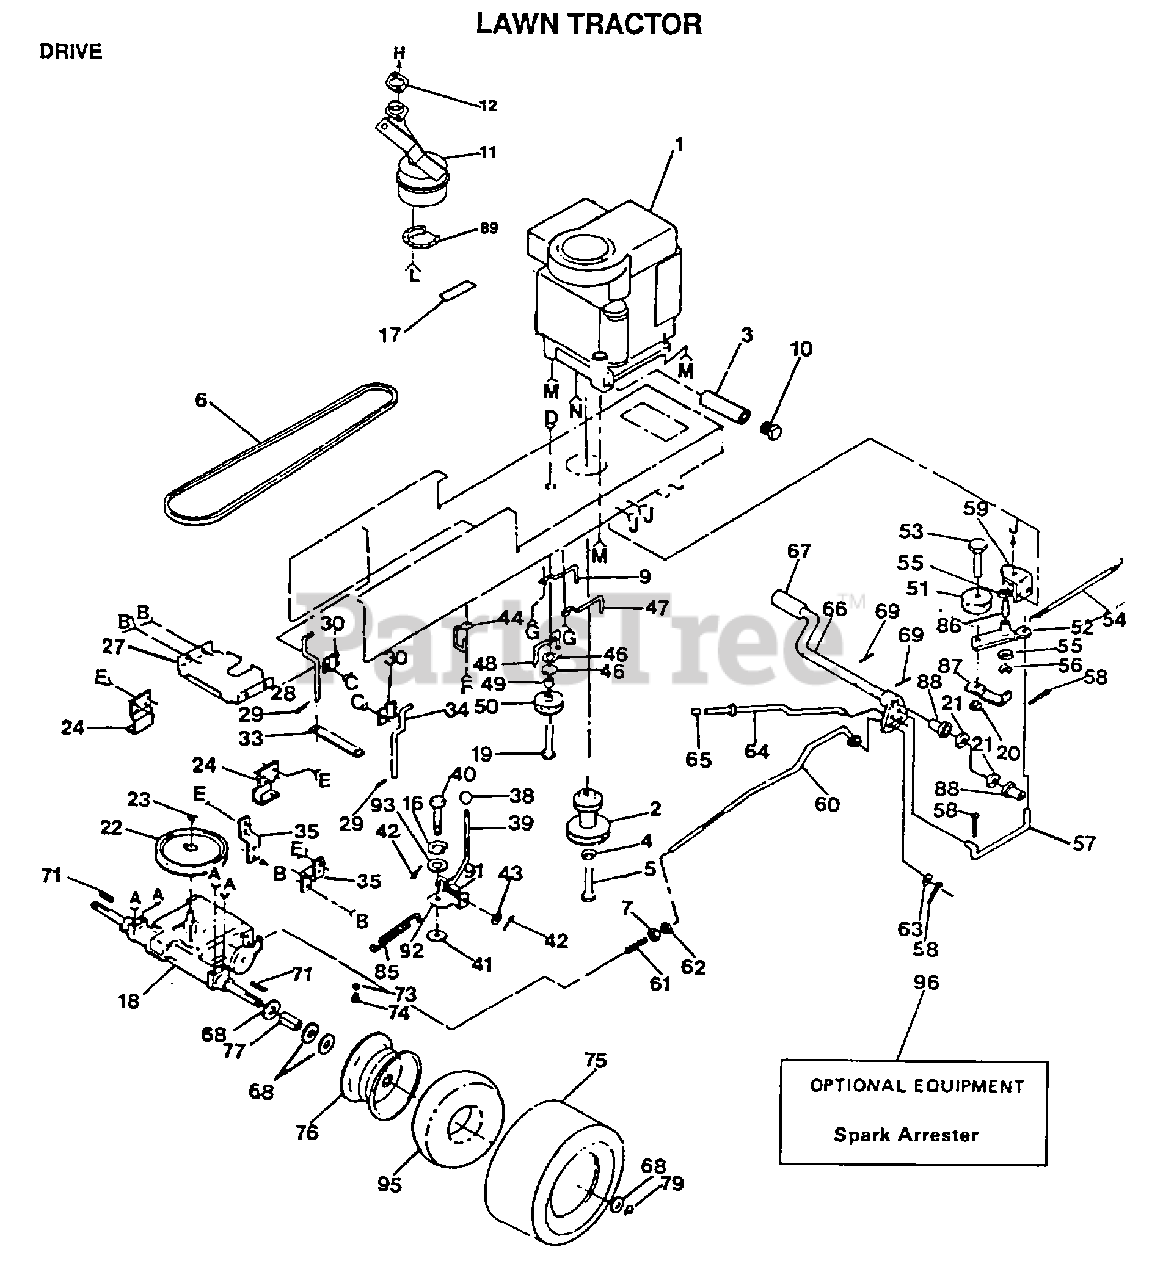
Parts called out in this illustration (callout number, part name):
3	"PIPE, DRAIN OIL"
4	LOCKWASHER
6	BELT-V.90.0.GD.DR
7	NUT
9	KEEPER BELT ENGLH
16	LOCKWASHER
19	BOLT
21	WASHER LT
22	PULLEY TRANS
24	BRACKET LT
27	BRKT SUPPORT LT
28	KEEPER BELT LH
29	SPRING.RETAINER
30	CLAMP LT
33	STRAP LOCATOR
34	KEEPER BELTRH
35	STRAP TORQUE
38	CONTROL KNOB LT
39	ROD SHIFTER
41	WASH-SHFT PLT LT
42	PIN COTTER 1/8
43	WASHER
46	WASHER
47	"KEEPER,BLT ENG LT"
48	BELT KEEPER LT
49	SPACER T
50	PULLEY.IDLER.FLAT
52	ARM IDLER
54	"SPRING, RETURN LT"
55	WASHER LT
56	KLIP RING
57	"LINK, CLUTCH T"
58	COTTER PIN
59	BRKT ASM
60	BRAKE ROD LT
61	SPRING ROD LT
62	NUT
63	WASHER
67	PEDAL COVER T
68	WASHER
71	SQUARE KEY
73	VALVE CAP
74	VALVE STEM LT
75	TIRE.TS2.18X8.5
77	SPACER LT
79	E-RING LT
86	"LY, BEARING"
87	RETAIN BELT
88	NYLON BEARING
89	DEFLECTOR.222573
91	SPRING LT
92	PLATE SHIFT LT
93	WASHER LT
95	TUBE.18X9.5-8
96	SPARK ARRESTER
